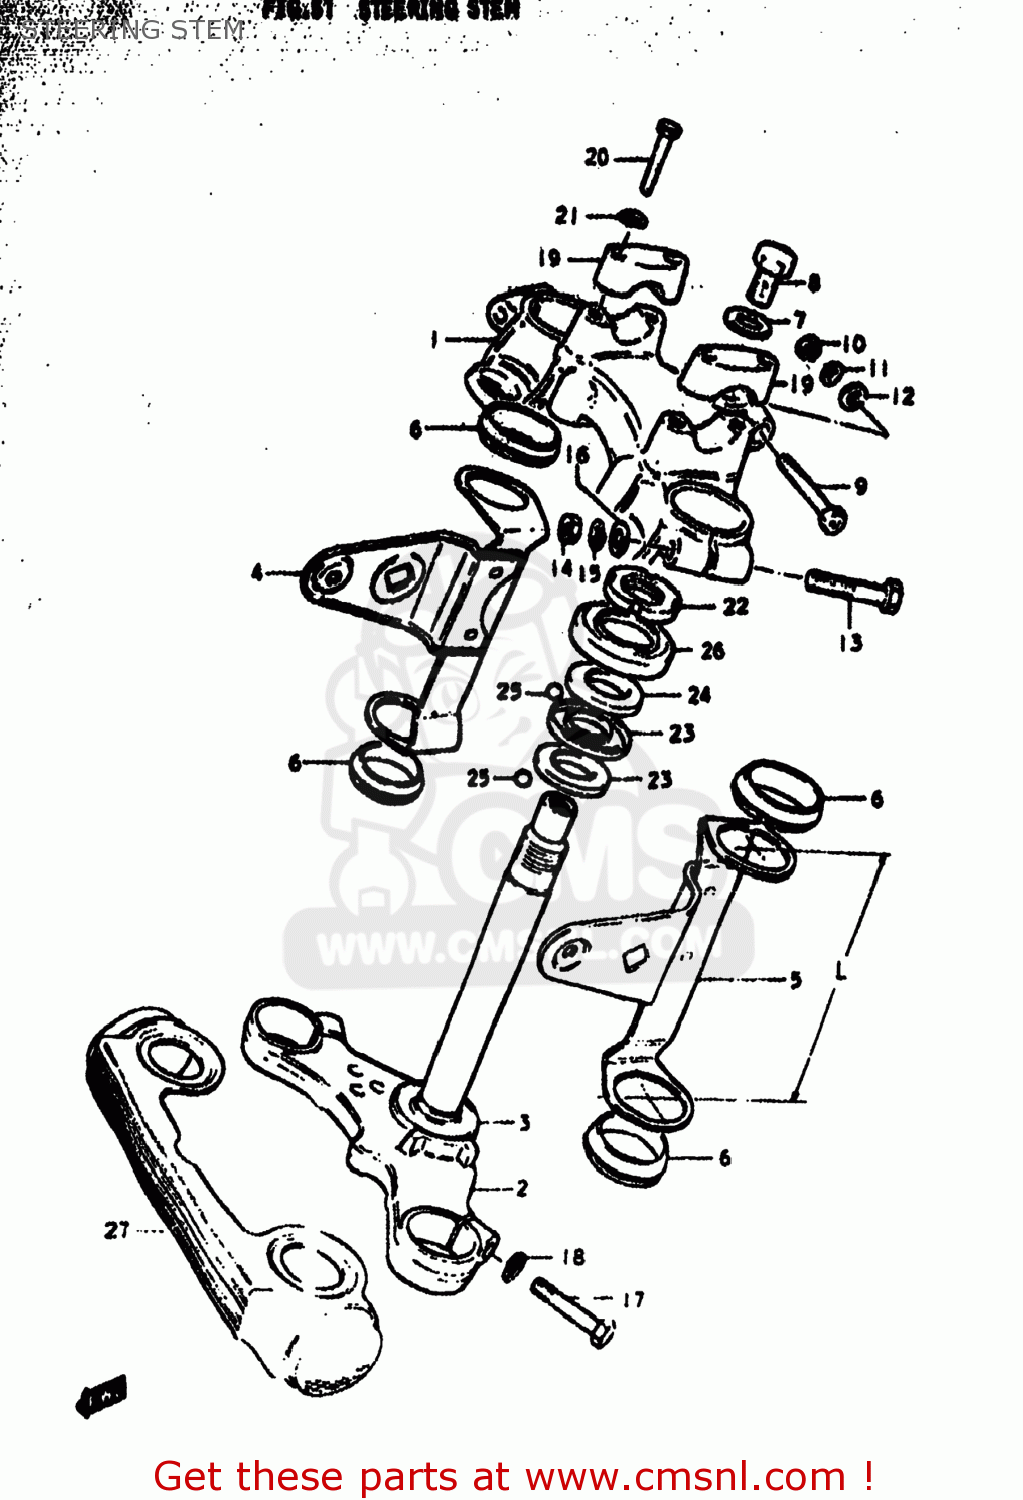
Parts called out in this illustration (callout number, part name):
1	HEAD,STEERING STEM
2	STEM,STEERING
3	RACE,STEERING OUTER LWR
4	BRACKET,HEADLAMP,RIGHT
5	BRACKET,HEADLAMP,LEFT
6	CUSHION,HEADLAMP BRACKET
7	WASHER
8	BOLT(12X20)
9	BOLT
10	NUT
11	LOCK WASHER
12	WASHER
13	BOLT 10X55
14	NUT
15	LOCK WASHER
16	WASHER
17	BOLT 10X40
18	LOCK WASHER
19	HOLDER,HANDLE UPR
20	BOLT
21	LOCK WASHER
22	NUT,STEERING STEM(25X44X10)
23	LACE,STEERING INNER LWR
24	LACE,STEERING OUTER UPR
25	BALL
26	DUST SEAL,STEERING,UPPER
27	COVER,FR FORK
